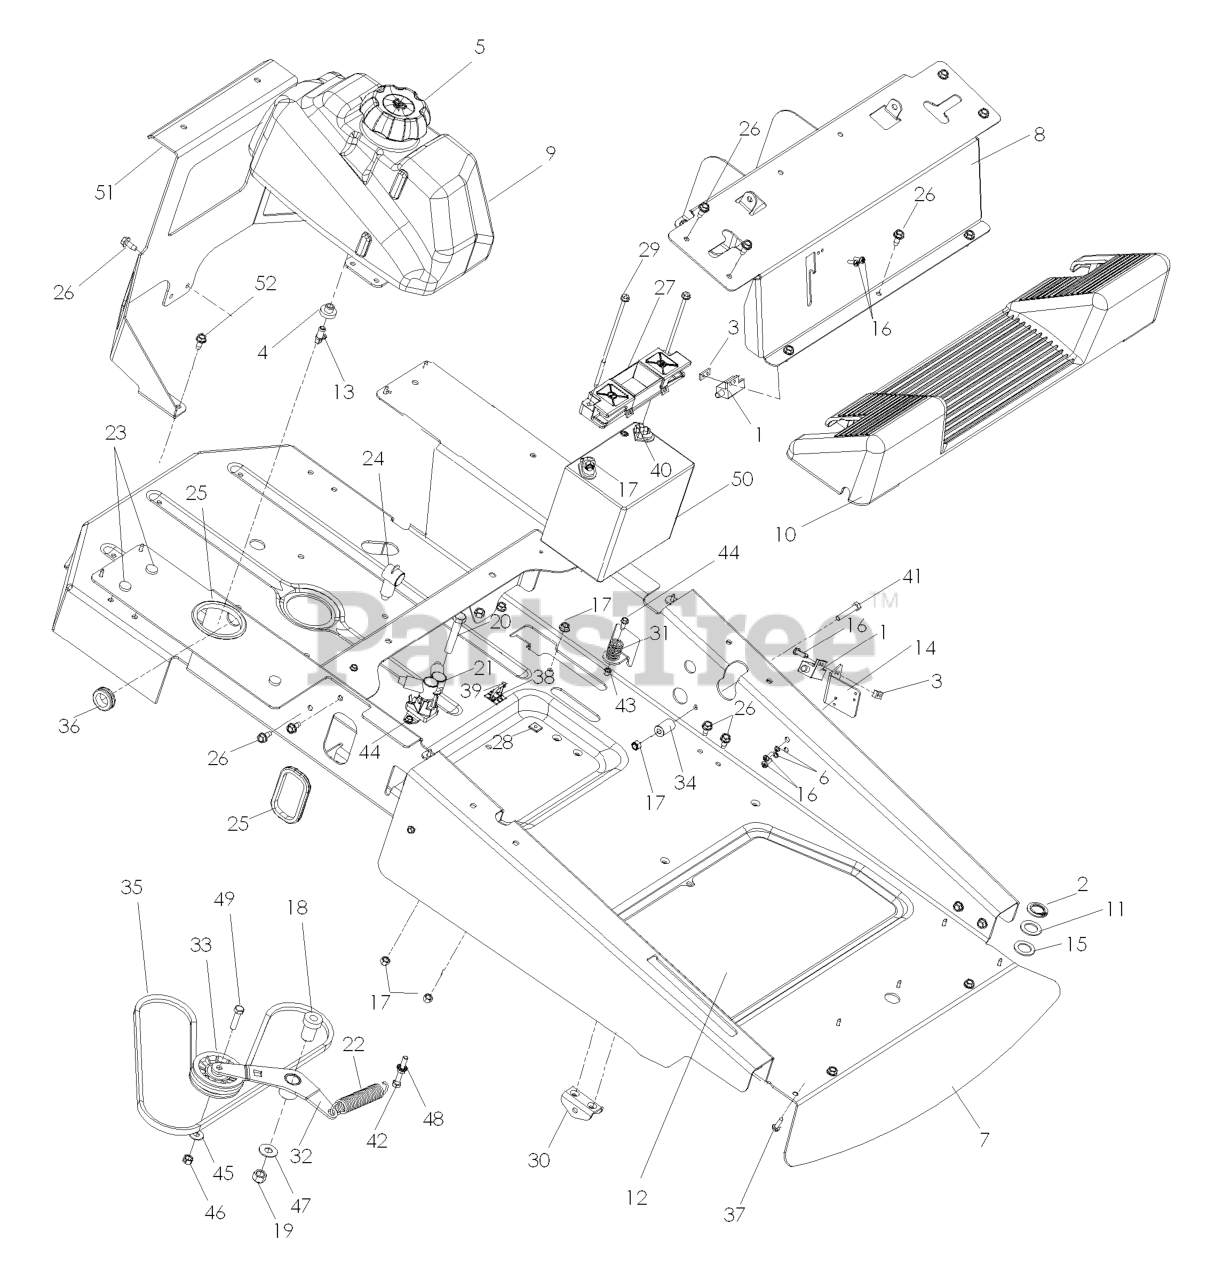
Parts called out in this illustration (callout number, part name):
1	SWITCH, INTERLOCK
2	RETAINING RING, 7/8"
3	TAPPED PLATE
4	RUBBER GROMMET
5	FUEL CAP ANTI-SPLASH
6	WASHER - 3/16 LOCK ZD
7	FRAME W/DECALS
8	SEAT SUPPORT W/DECALS
10	FOOT REST GRAY
12	SLIP, MATTING
13	STEM, FUEL TANK
15	BSHG .875 X 1.375 X .074 ZD
16	SCREW #10-24 X 5/8
17	NUT 5/16 NYLOC
18	IDLER SPINDLE
19	NUT 1/2-13 HEX NYLOC ZD
20	HCS 1/2C X 2 3/4
23	GROMMET, BUMPER
26	BOLT 5/16-18 X 3/4
27	BATTERY HOLD DOWN
28	PUSH NUT-NYLON
29	BOLT - 1/4-20 X 7.5
30	BRACKET, DECK HANGER
31	SPRING, RETURN TO NEUTRAL
32	PUMP IDLER WELDMENT
33	PULLEY, IDLER RAKE & ZTR
34	MOTION LIMITER
35	BELT, HYDRO PUMP
36	GROMMET, FUEL LINE
37	SCR #10-12X1-1/2HEX WASH HD ZD
38	MOUNTING BLOCK CABLE TIE
39	TIE, PLASTIC
40	HCS 5/16C X 3/4
41	HCS 5/16-18X2
43	NUT.1/4-20.HEX.NYLOC.ZD
44	SCREW 1/4 X 5/8
45	WASHER 3/8 FLAT
46	NUT 3/8C CENTERBLOCK
47	WASHER 1/2 FLAT
48	NUT 5/16C WHIZ
49	HCS 3/8C X 1 1/2
50	BATTERY, 12 V 330 AMP
51	REAR BRKT, TOOL BOX, PAINTED
